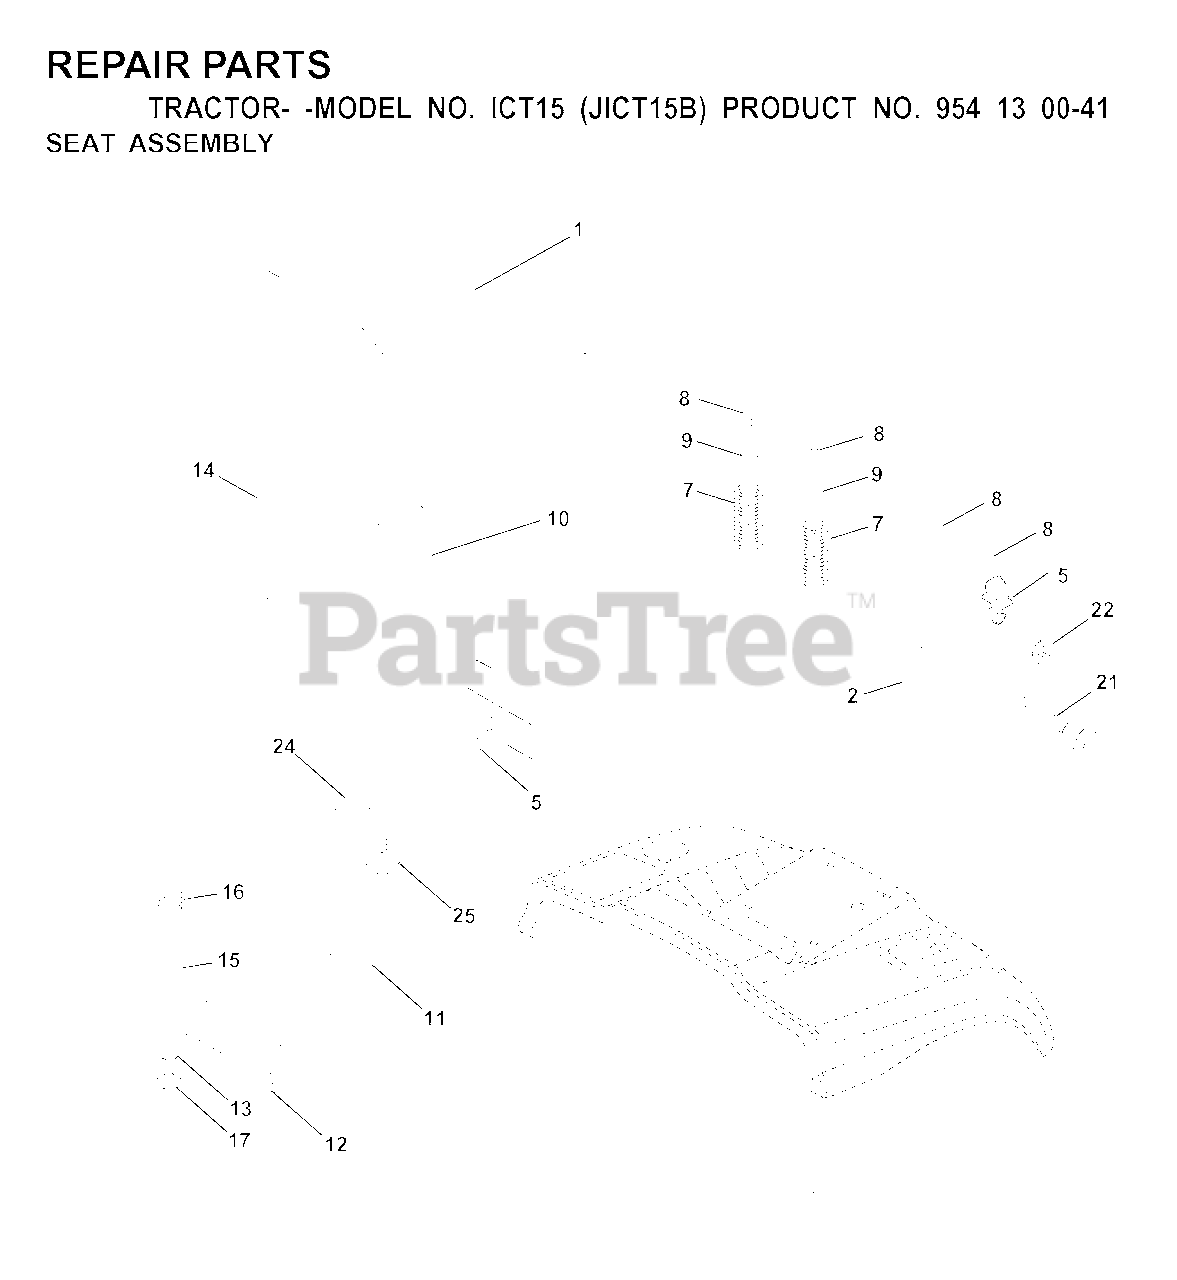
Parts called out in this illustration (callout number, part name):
2	SEAT PIVOT BRKT
5	PUSH CLIP
7	SPRING COMPRESSION
8	SCREW 3/8-16X1
9	WASHER
10	PAN, SEAT
11	KNOB.SEAT.ADJ.WINGNUT
12	BRKT SWITCH
14	BOLT.ROUND.HEAD.SQUARE.NECK
15	SPACER SPLIT
16	SPRING COMPRESSED
17	NUT T
21	BOLT.SHOULDER.5/16-18
22	NUT.71038.31-18.HEX.NYLOCK
25	BOLT,SHOULD
